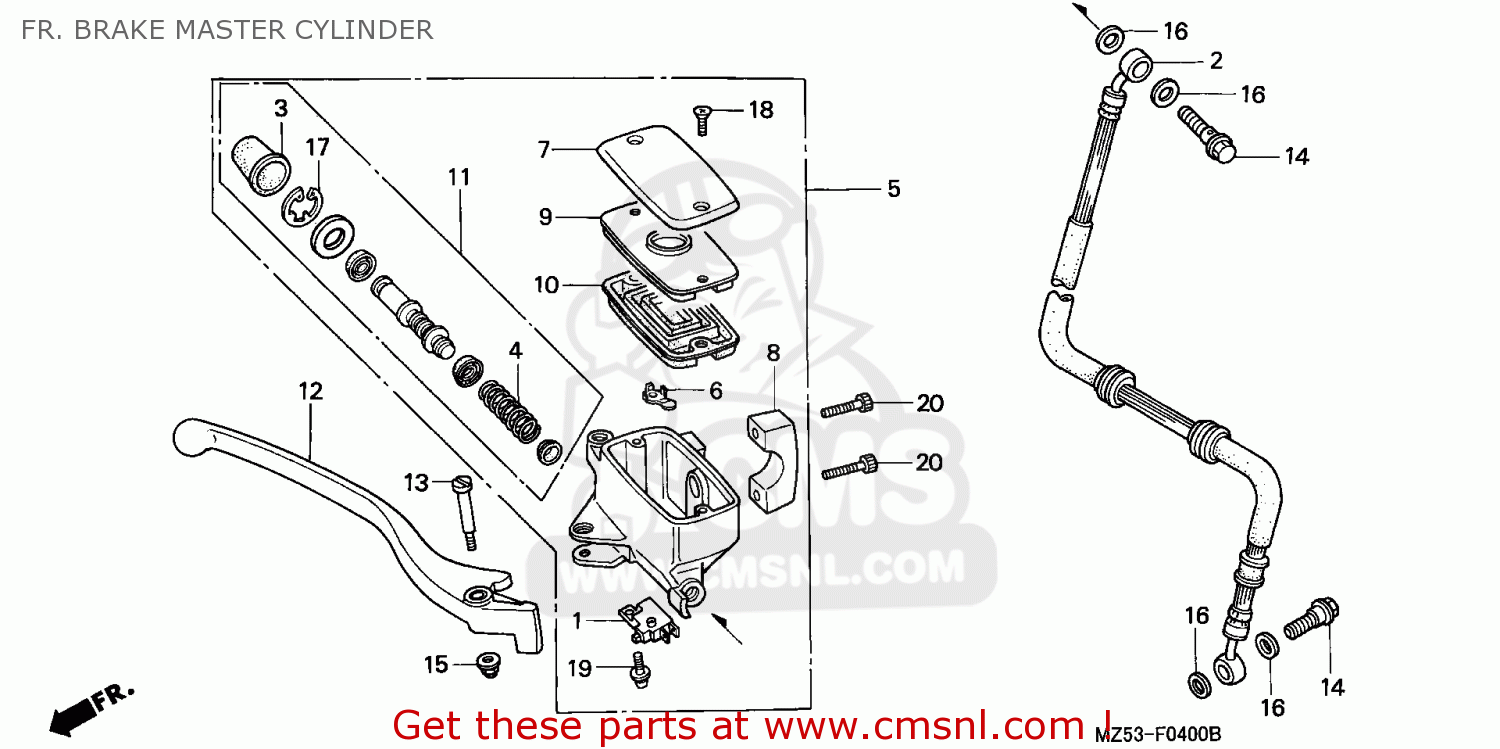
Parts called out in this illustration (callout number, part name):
1	SW ASSY,FR STOP
2	HOSE COMP,FR BRK
3	BOOT COMP.
4	SPRING
5	SUB ASSY,FR M/C
6	PROTECTOR
7	CAP,MASTER CYLIND
8	HOLDER,M/C
9	PLATE,DIAPHRAGM
10	DIAPHRAGM
11	CYLINDER SET,MAST
12	LEVER COMP.,R.HAN
13	BOLT,HNDL PIVOT
14	BOLT,OIL,10X22
15	NUT,CAP,6MM
17	CIRCLIP
18	SCREW,FLAT 4X12
19	SCREW-WASHER,4X12
20	BOLT,SOCKET,6X22
